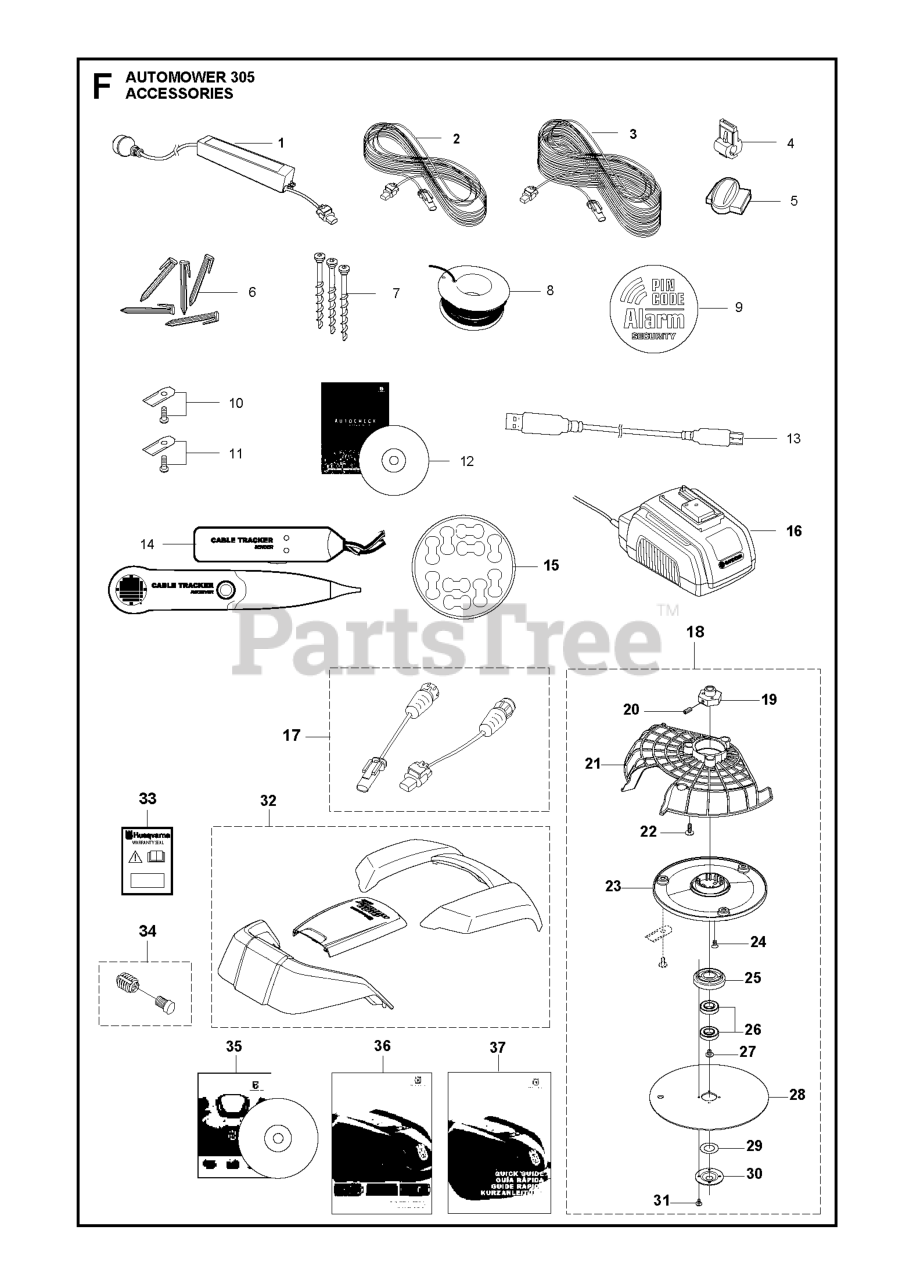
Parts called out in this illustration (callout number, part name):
4	CONNECTOR 5 PCS, BLISTER
4	BRAKER
5	COUPLER SPLICER, 100 PCS
5	COUPLER SPLICER, 5 PCS,
5	SPLICE KIT
6	STAPLE 100 PCS, BLISTER
6	STAPLE 100 PCS
7	SCREW KIT KIT INCLUDES THREE S
7	SCREW 3 PCS, BLISTER PACK
8	LOOP WIRE 150M
8	WIRE 250M
8	WIRE 150M, BLISTER
9	LABEL SECURITY
10	BLADE - 30 PCS
10	BLADE KIT
10	BLADE
10	BLADE - BULK PACK 500 PCS
11	BLADE 300PCS -SINGLE HOLE THIC
11	BLADE 9PCS EXTRA THICK
11	BLADE BLADE KIT INCL PACKAGING
11	BLADE CARBON STEEL, THICK BLAD
14	TEST EQUIPMENT
15	STICKER CABLE MARKERS KIT 10PC
20	SCREW IHSETM M5X10 8.8 ZP-BC
22	SCREW 14MM
24	SCREW
26	BALL BEARING BALL BEARING 535
30	COVER SKID PLATE
31	SCREW SILVER 10MM
33	LABEL WARRANTY SEAL DEALER
33	LABEL WARRANTY SEAL KIT 10 PK
34	THREAD INSERT KIT: THREAD INSE
